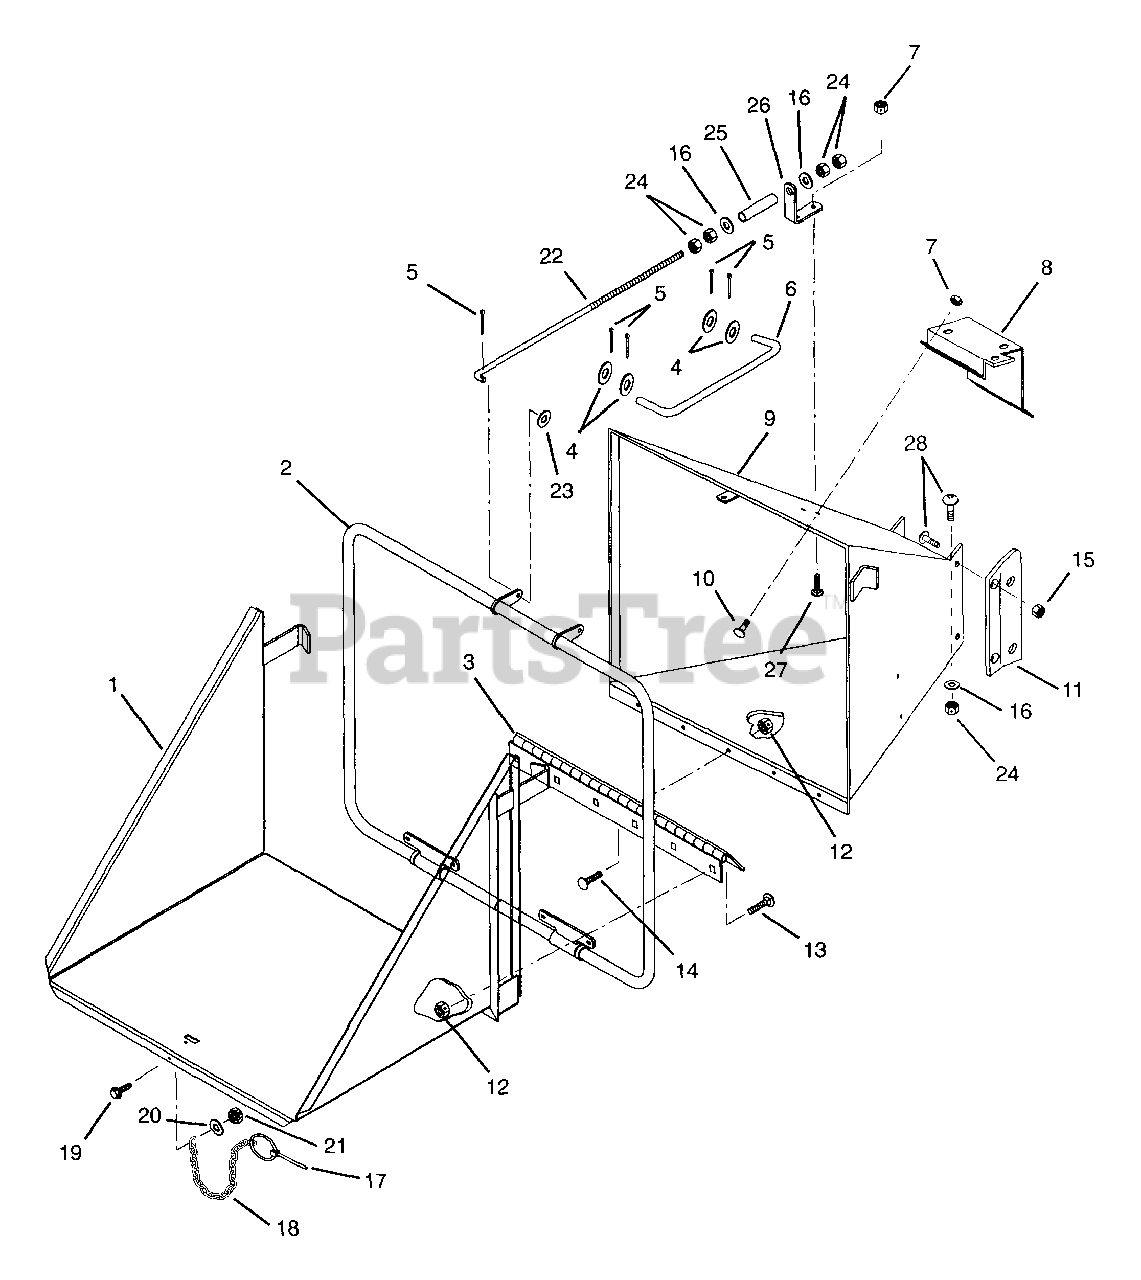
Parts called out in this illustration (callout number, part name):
1	Apron Weldment
2	Loop Weldment
4	Washer-Flat-Steel .406 x .812 x .065
5	Pin-Cotter .12 X .75
7	Nut-Locking .312-18
8	Valve Mount
10	Bolt-Round Head-Square Neck-.312-18 x 1.00 Gr 5
11	Left Hand Support
11	Right Hand Support
12	Nut-Locking-Center .250-20
13	Bolt-Round Head Square Neck .25-20 x .50
14	Bolt-Round Head Square Neck .25-20 x .75
15	Nut - Locking-Center .38-16
16	Washer-Flat-Steel .438 x 1.00 x .083
17	Pin-Lock .31 x 2.00
18	Chain-5 Straight Link #4
19	Screw-Machine 10-24 x .75 w/ Insert
20	Washer-Flat-Steel .219 x .50 x .049
21	Nut-Lock-10-24 w/ Insert
22	Rod-Valve Stop
23	Washer-Flat-Steel .344 x .688 x .065
24	Nut-Hex .38-16
25	Tubing-Urethane .438 x .688
26	Bracket-Valve Stop
27	Bolt-Round Head-Square Neck .312-18 x .75
28	Screw, Socket-Button Head .38-16 x 1.00
